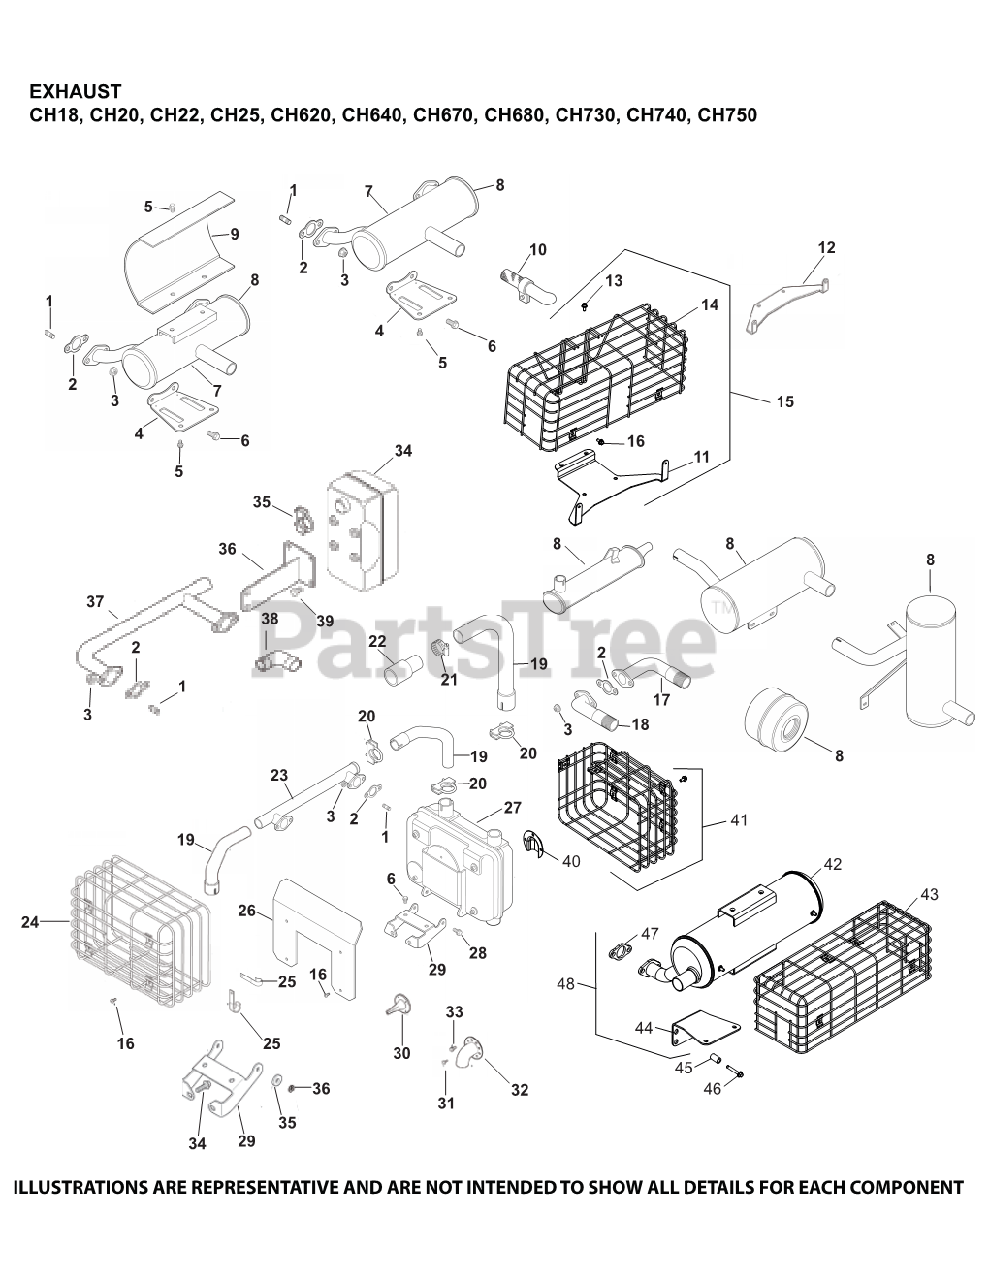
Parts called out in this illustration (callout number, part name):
2	GASKET, EXHAUST
3	NUT, FLG M8X1.25
5	SCREW, FLG M6X1.0X12
6	SCREW, FLG M8X1.25X20
